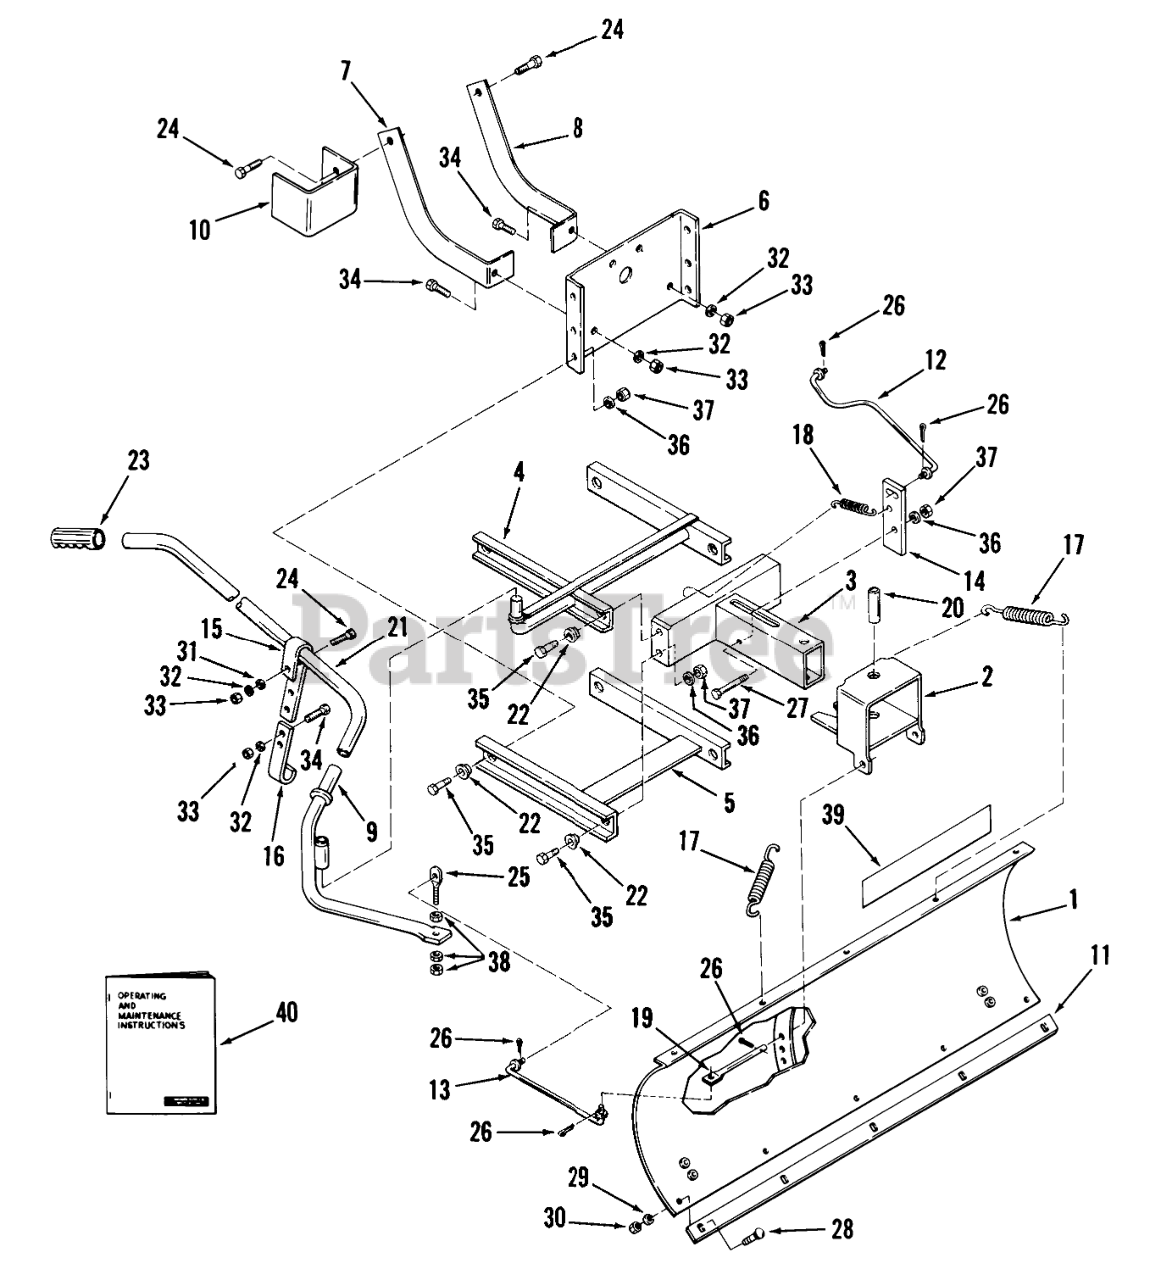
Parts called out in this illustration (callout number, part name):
1	Blade
2	Quadrant
3	Frame
4	Upper Parallel Bar
5	Lower Parallel Bar
6	Frame Mount
7	R.H. Frame Mount Brace
8	L.H. Frame Mount Brace
9	Lower Handle
10	Latch Bracket
11	Blade Edge
12	LINK INDEX
13	Pivot Link
14	Index Bar
15	Upper Latch
16	Lower Latch
17	Trip Spring
18	SPRING-TENSION
19	PIN-QUADRANT
20	ROD-QUADRANT
21	Extension Handle
22	SPACER-PAR BAR
23	GRIP-HANDLE BAR
24	Bolt
25	Eye Bolt
27	Bolt
28	Bolt-Carriage
29	Washer
30	Nut
31	WASHER 5/16 SAE
32	Lockwasher
33	Nut
34	Bolt
35	BOLT
36	LOCKWASHER
37	Nut
38	Nut
39	Decal-Rear
40	Operating and Maintenance Instructions
